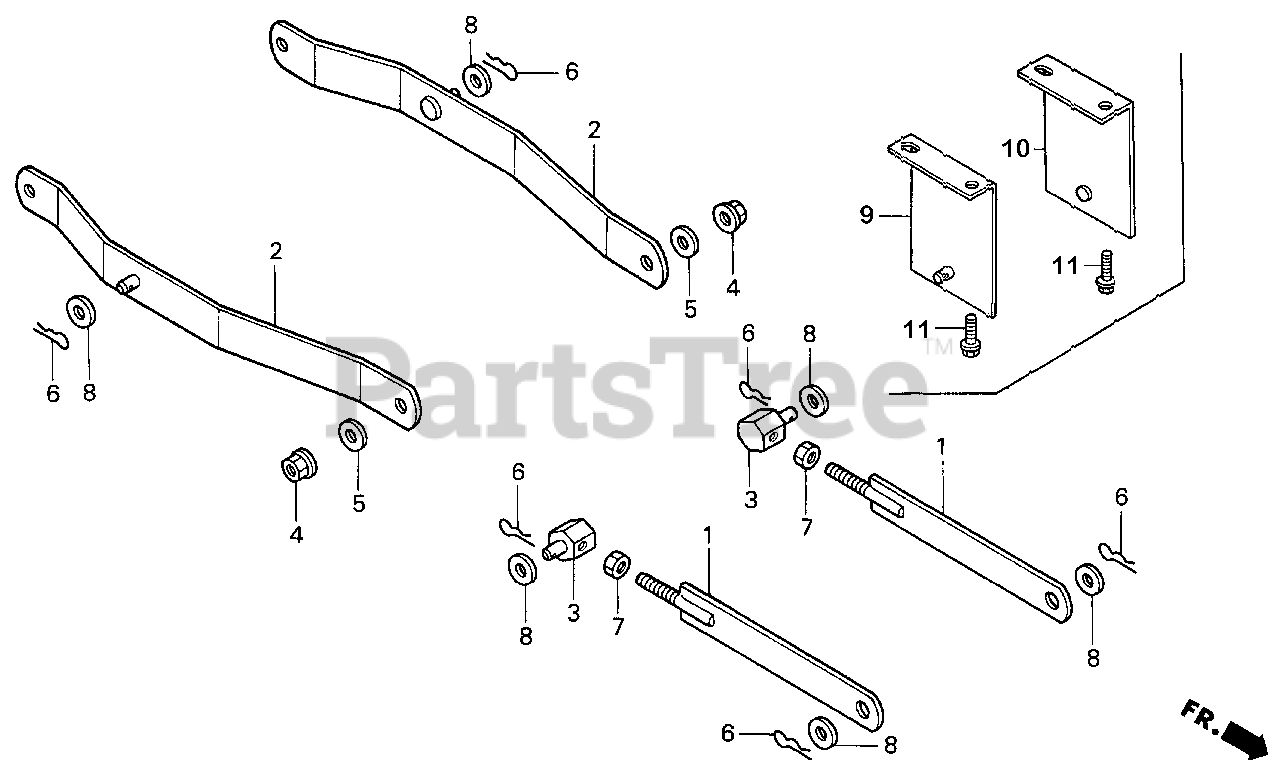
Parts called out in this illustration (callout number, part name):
1	LINK, FR. DECK
2	LINK, RR. DECK
3	PIN, FR. LINK ADJUSTING
4	NUT, U (10MM)
5	WASHER (10.5X27X4)
6	PIN, LOCK (14MM)
7	NUT, HEX. (12MM)
8	WASHER, FLAT (14MM)
9	BRACKET, R. ROLLER
10	BRACKET, L. ROLLER
11	BOLT, FLANGE (10X25)
